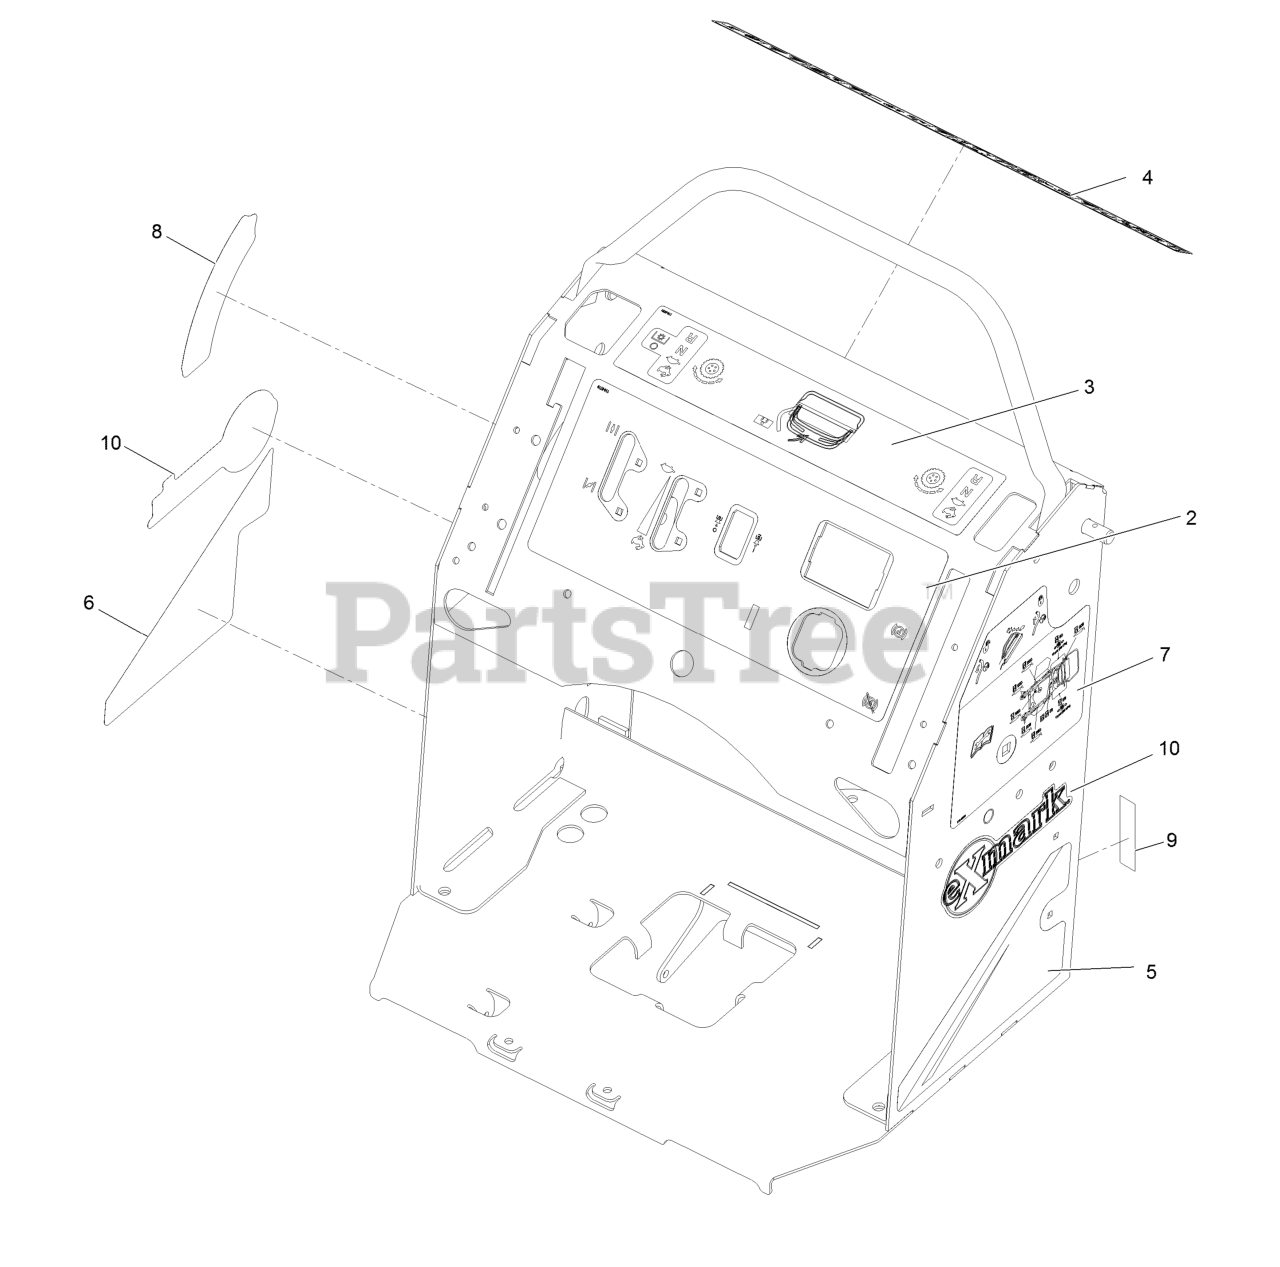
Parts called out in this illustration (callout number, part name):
2	Decal-Control Panel
3	Decal-Motion Control
4	Decal-Warning
5	Decal-LH Panel
6	Decal-RH Panel
7	Decal-Service Aid
8	Decal-Height Of Cut
9	Decal-Fuse
10	Decal-Exmark Logo
